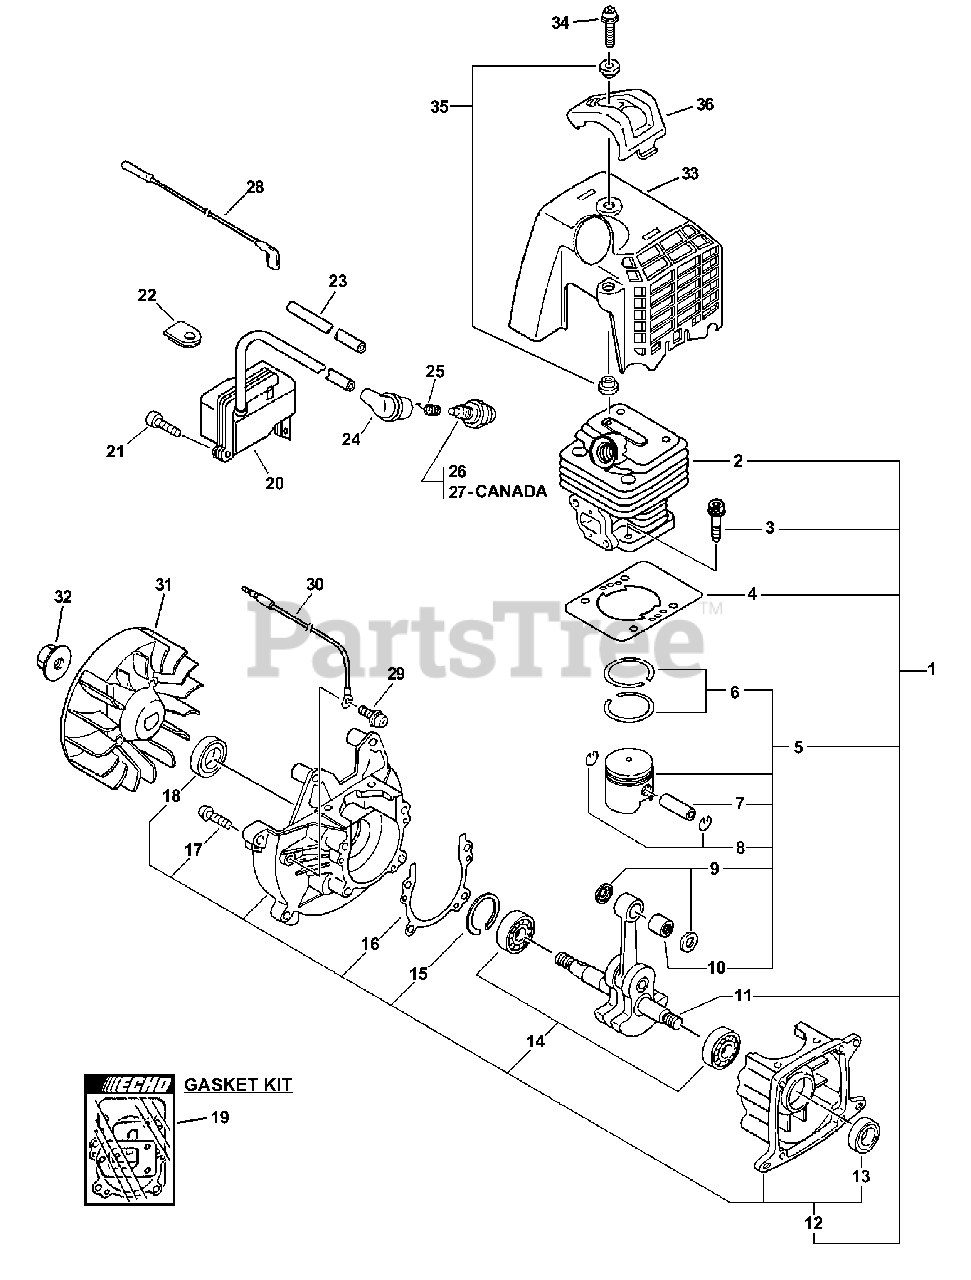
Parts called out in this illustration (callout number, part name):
1	SHORT BLOCK -- SB1061
2	CYLINDER
3	SCREW - 5X22
4	GASKET, CYLINDER
5	PISTON KIT
6	RING, PISTON
7	PIN, PISTON
8	RING, RETAINING
9	SPACER, PISTON
10	BEARING, NEEDLE - 8
11	CRANKSHAFT ASSY
12	CRANKCASE KIT
13	SEAL, OIL
14	BEARING, BALL - 6001C3
15	RING, RETAINING - 28
16	GASKET, CRANKCASE
17	SCREW - 5X25
18	SEAL, OIL - 12
19	GASKET KIT
20	COIL, IGNITION
21	SCREW - 5X16
23	TUBE, INSULATOR
24	CAP, SPARK PLUG
25	TERMINAL, SPARK PLUG CAP
26	SPARK PLUG -- BPM-8Y
27	SPARK PLUG -- BPMR-8Y
28	LEAD - IGNITION
29	SCREW - 5X10
30	LEAD - GROUND
31	FLYWHEEL
32	NUT - 8 -- FLANGE
33	COVER, ENGINE - ORANGE
34	SCREW - 5X16
35	COLLAR - 5
36	GUARD - TOP
